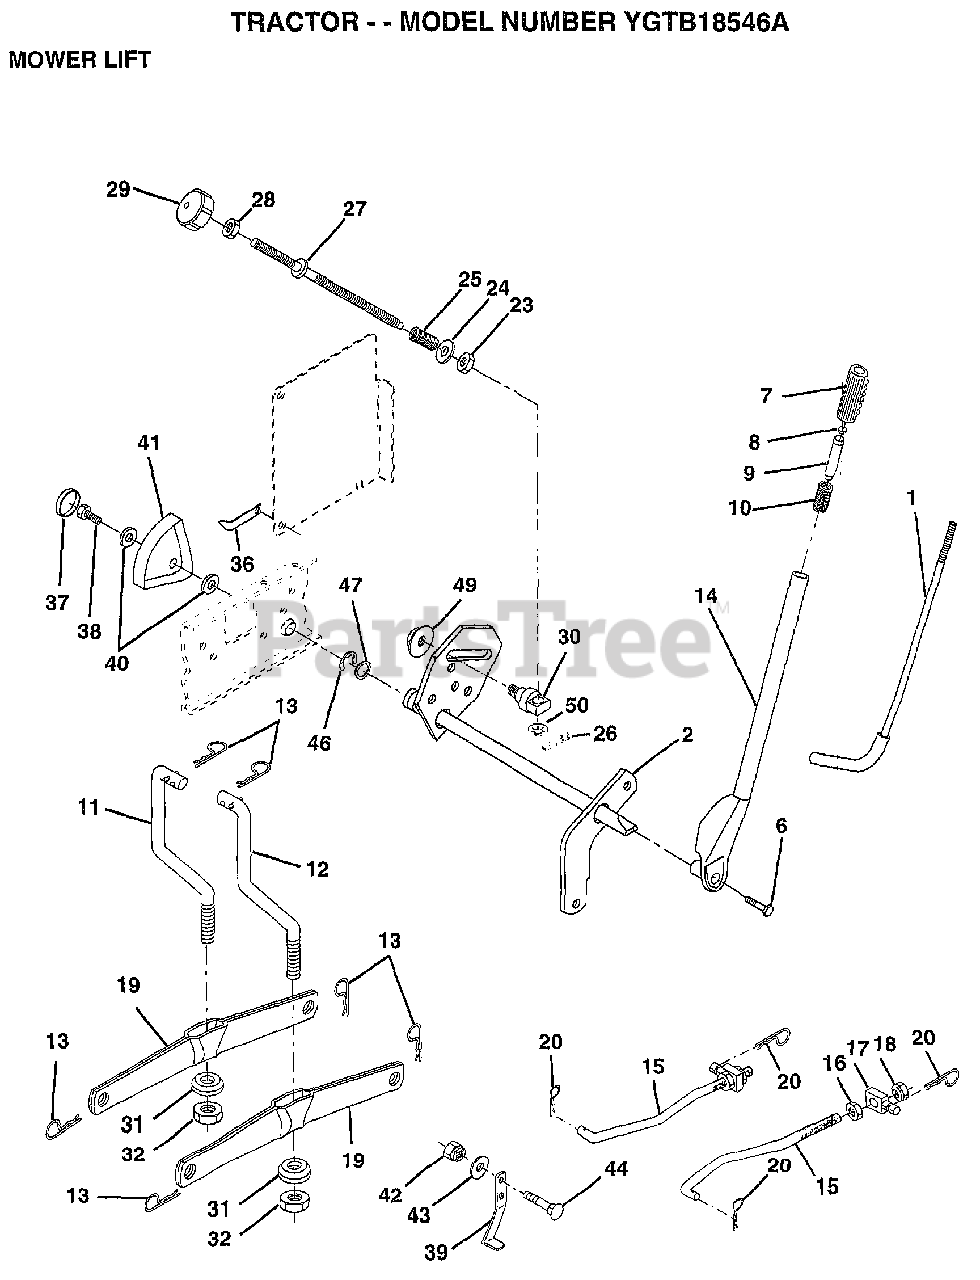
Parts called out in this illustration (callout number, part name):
1	LEVER ROD LT
2	LEVER ASSY LIFT.RH.
6	"BOLT,HEX"
7	GRIP HANDLE
10	SPRING T
11	LINK.LIFT.LH.GTV
12	LINK.LIFT.RH.GTV.
14	LEVER.ASM.LIFT.RH
15	LINK.FRONT
16	NUT
17	TRUNION
18	NUT LTV
19	ARM SUSP REAR
20	RETAINER SPRING
23	NUT T
24	WASHER
25	SPRING T
28	NUT
29	KNOB INF 3/8-16
30	TRUNNION
31	BEARING PVT LH
32	NUT.CROWNLOCK.3/8
36	POINTER HEIGHT INDICATOR
37	"PLUG,HOLE"
38	SCREW
39	STOP.OVER.CENTER
40	WASHER
41	HEIGHT INDICATOR
43	WASHER GT
44	BOLT
46	E-RING
47	WASHER
49	NUT.HXFLG.LOCK.
50	NUT PUSH M
